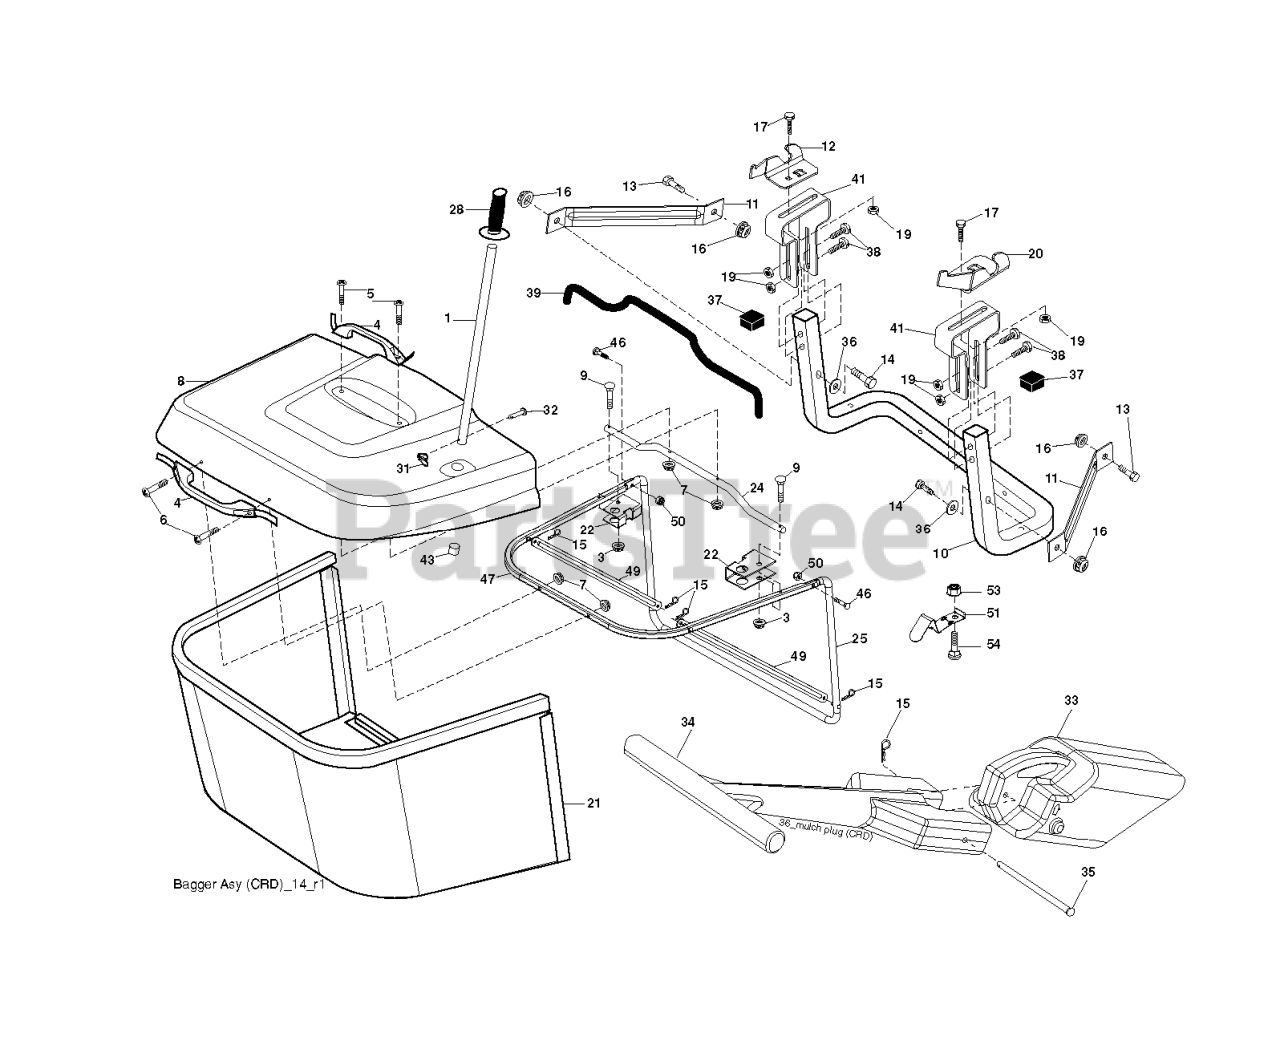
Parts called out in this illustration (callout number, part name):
1	TUBE HANDLE
3	NUT T
4	HANDLE.BAGGER.W/LVRS.BLK.CRD
5	SCREW.PAN.HEAD
6	REPL BY 532 75 00-29
8	COVER.PNT.BGR.CRD.WSLOTS.MS668
9	Bolt Carriage 1/4-20 x 2.25d x Gr.5
10	TUBE
11	BRACKET.SUPPORT.UPPER.BAG.CRD
12	BRKT PIVOT
14	BOLT-HEX EAK
15	RETAINER-SPRNG RB
16	NUT LOCK FLG 3/8-16 UNC
17	RP BOLT 5/16-18 X3/4 ZN/YEL GR
19	NUT LOCK HEX FLANGE 5/16-18
20	BRKT.PIVOT.RH.CRD
21	BAGGER.ASM.CRD.2007
22	BRKT.SIDE.BAG.CRD
24	TUBE.PIVOT.BAG.CRD.BLACK
25	PIPE
28	GRIP.HANDLE.BLACK
31	RETAINER CLIP
32	RIVET,DRILLED
33	MULCH PLUG, CTH150
34	HANDLE.MULCHER.92.CRD (2 2)
36	WASHER
37	Plug Support Bagger CRD
38	BOLT.5/16-18X2.5
39	SEAL.BAGGER.CRD
41	BRKT.VERT.ADJ.BAGGER.CRD
43	PLUG, TUBING END
46	BOLT.CARRIAGE.5/16-18
47	PIPE
49	ROD
50	NUT.71038.31-18.HEX.NYLOCK
51	LATCH
53	NUT
54	BOLT
